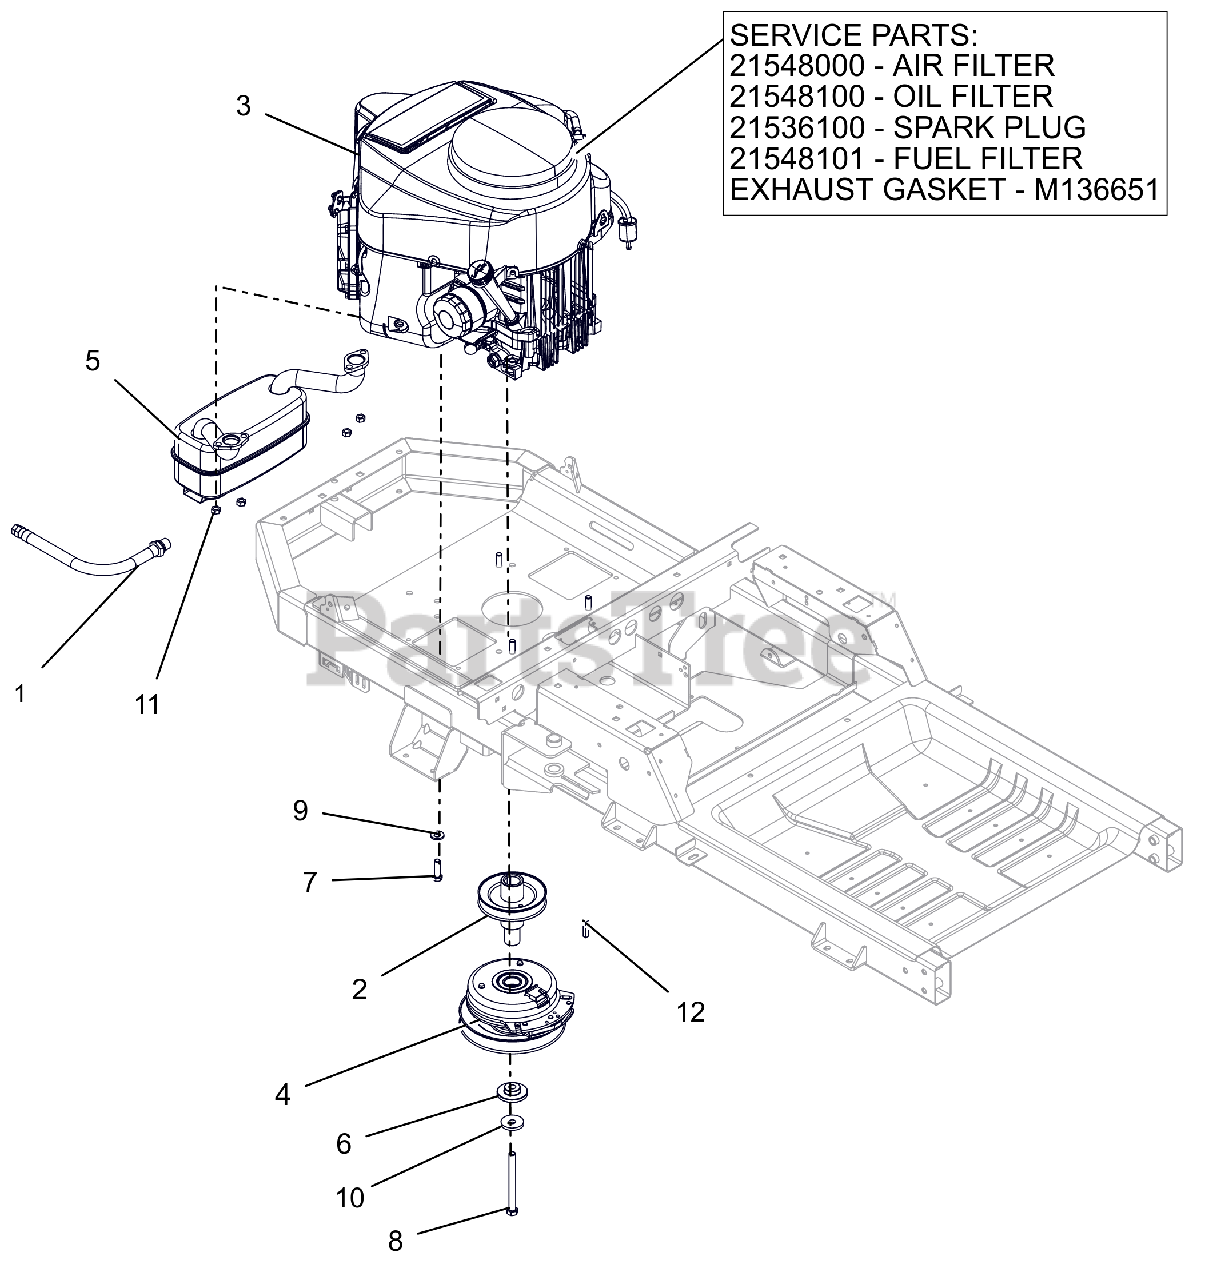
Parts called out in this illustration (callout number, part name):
1	HOSE, OIL DRAIN
2	WLDMT, DRIVE SHEAVE-X
3	AIR FILTER, KAWASAKI FR
3	OIL FILTER, KAWASAKI FR
3	PLUG, SPARK
3	FUEL FILTER-KAWASAKI FR
3	GASKET, MUFFLER #
4	CLUTCH,105FTLB MONOPOLE 6.83"
5	MUFFLER - KAWASAKI
6	BSHG-FLG .469X1.06X.574X2.0
7	BLT-HEX.38-16X1.25 G5YZ NYTORQ
8	BLT-HEX.438-20X4.5GR8YZ NYTORQ
9	WASHER, 3/8" SPRING DISC
10	WASHER, 7/16" SPRING DISK
11	NUT-LK-TOP M8-1.25 YWZC
12	KEY-SQ .25 X 1.25 X .25 SAE
